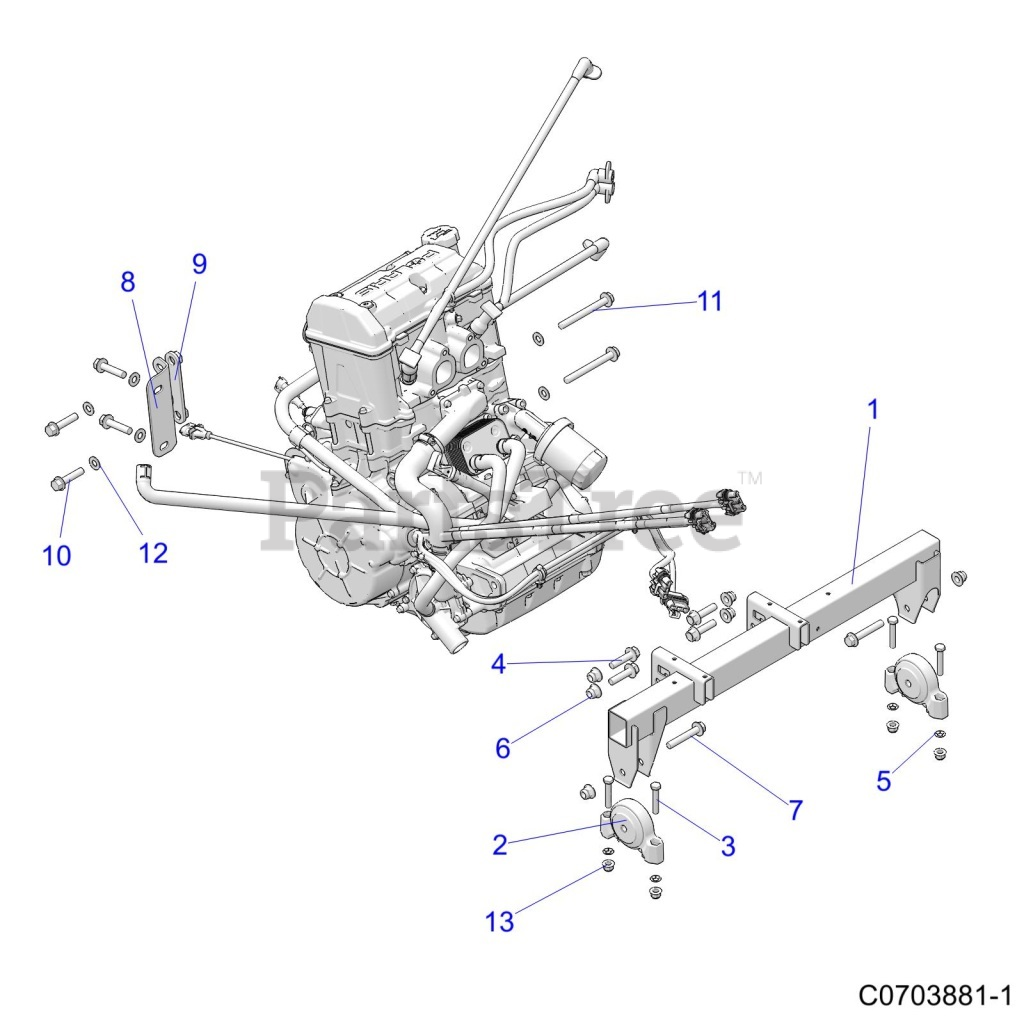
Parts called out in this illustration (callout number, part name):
1	WELD-MOUNT,ENGINE,BLK
2	MOUNT-ISOLATOR,DRIVELINE
3	SCR-HH M8X1.25X45 8.8 ZOD
4	SCR-HXFL-M10X1.25X40 8.8 ZOD
6	NUT-M10X1.25,FLG,NYLOC-OLIVE D
7	BOLT-M10X1.25X60,HXFLG-OLIVE D
8	BRKT-COUPLER,TRANS
9	WELD-NUT,PLATE
10	SCR-HXFL-M10X1.25X45 8.8 ZOD
11	SCR-HXFL-M10X1.25X95 10.9 ZOD
12	WASHER,3/8 FW
13	NUT-M8X1.25,FLG,NYLOC-OLIVE D
